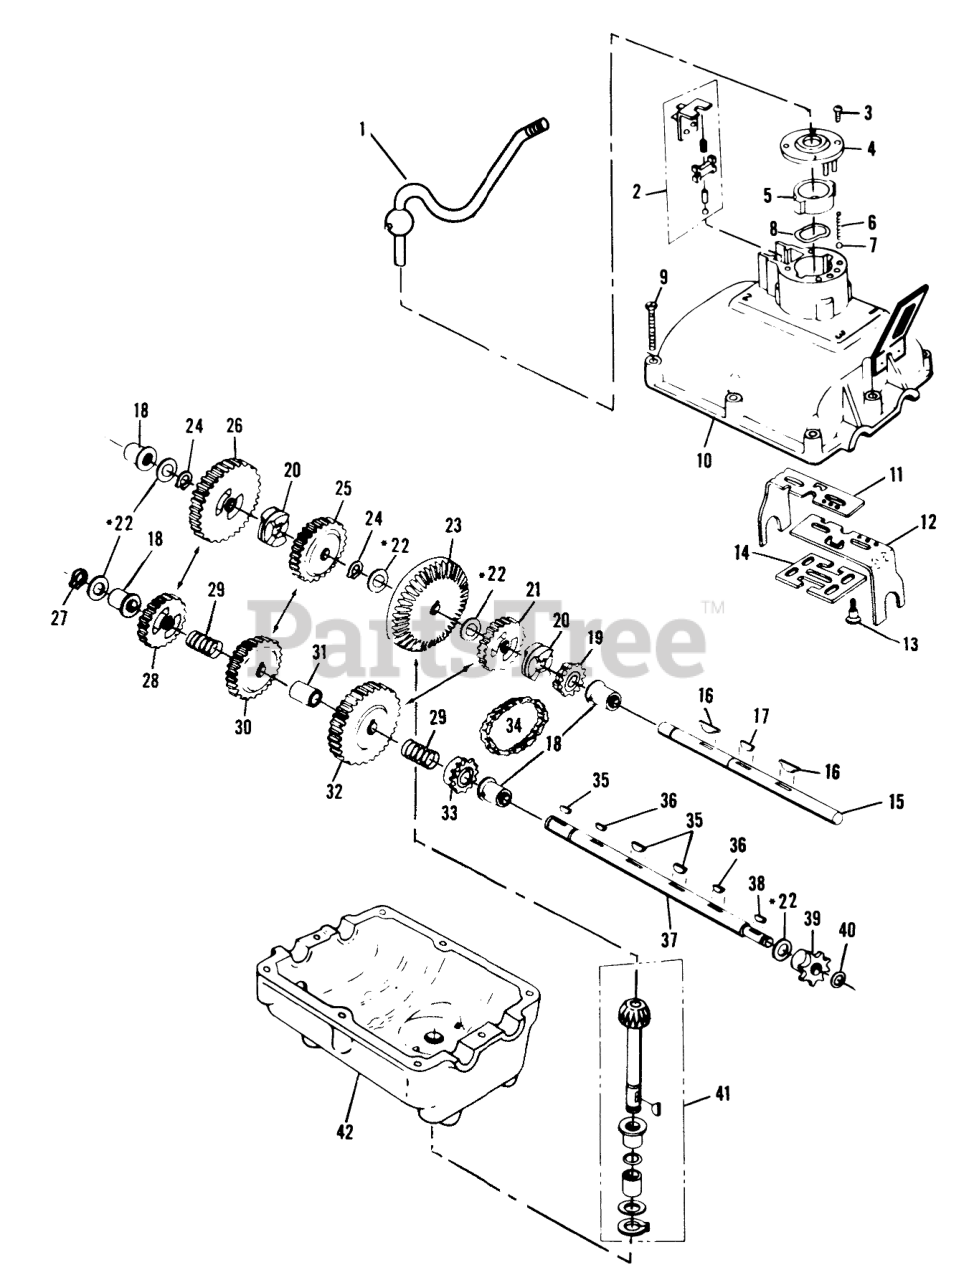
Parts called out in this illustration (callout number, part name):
1	Shift Lever Assembly
2	Switch Assembly, Kit
3	Screw, Truss Hd, 10-24 x 1/2 In.
4	Cover, Nylon
5	Insert, Nylon
6	Spring, Detent
7	Bail, Detent
8	Wave Washer
9	Screw, Hex Hd, 1/4-20 x 1-5/16 In.
10	Housing, Upper
11	Fork, Shifter, R.H.
12	Fork, Shifter, L.H.
13	Screw, Shoulder
14	Plate, Shifter Lockout
15	Shaft, Drive
16	Key, Hi-Pro
17	Key, Woodruff
18	Bearing, Flange
19	Sprocket, 12-Tooth
20	Collar, Clutch
22	Washer .031 Thk
22	Washer .040 Thk
22	Washer .050 Thk
22	Washer .060 Thk
22	Washer .025 Thk
22	Washer .035 Thk
22	Washer .045 Thk
22	Washer .020 Thk
23	Gear, Bevel 42-Tooth
24	Snap Ring
25	Gear 25-Tooth
26	Gear 30-Tooth
27	"E" Ring
28	Gear 20-Tooth
29	Spring, Compression
30	Gear 25-Tooth
31	Spacer
32	Gear 30-Tooth
33	Sprocket, 12-Tooth
34	Chain, 22 Pitches
35	Key, Woodruff
36	Key, Woodruff
37	Shaft, Output
38	Key, Woodruff
39	Sprocket, 8-Tooth
40	Ring, Retaining
41	Input Shaft Assy, Kit
42	Housing, Lower
72	Tag, Warranty (Not Illustr.)
